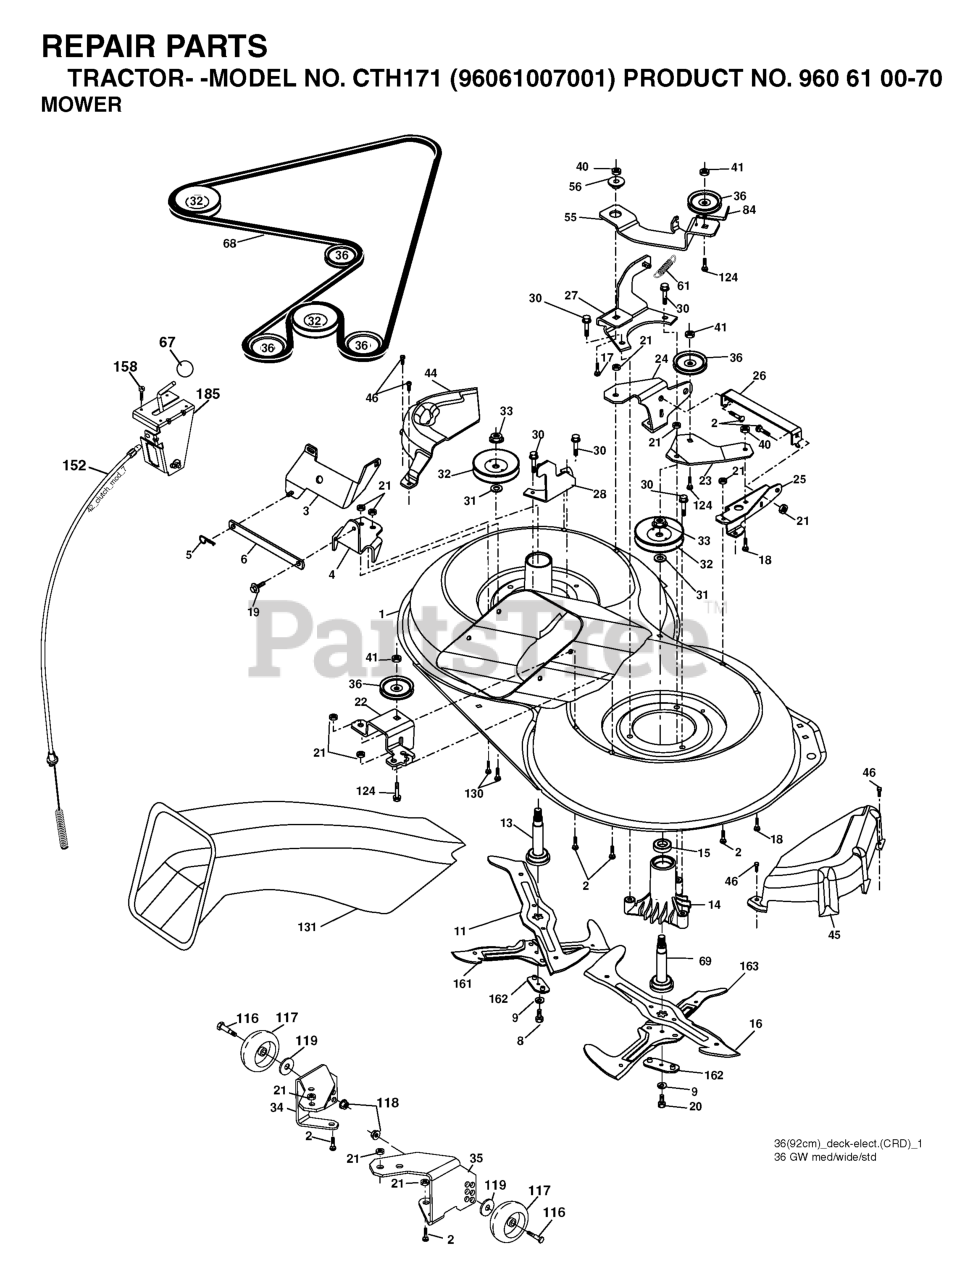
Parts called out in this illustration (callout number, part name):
2	RP BOLT 5/16-18 X3/4 ZN/YEL GR
5	RETAINER-SPRNG RB
6	BAR.SWAY.92.CRD
8	BOLT.3/8-24X1.25 GR8
9	LOCKWASHER
13	SHAFT ASM VENT
14	HOUSING.MANDREL.VENTED (MACHD)
17	BOLT.3/8-14X1.25
19	BOLT SHD 5/16-18
20	BOLT.3/8-24X1.25GR8. LHTHRD
21	LOCKNUT
26	SUPPORT
30	SCREW, WASHER HEAD
31	WASHER.SPACER.MANDREL
32	PULLEY, MANDREL
33	NUT.FLANGE.LOCK.TOP
36	PULLEY.IDLER.4.25
41	NUT LOCK FLG 3/8-16 UNC
45	COVER.MANDREL.RH.CRD
46	SCREW.1/4-20X5/8
55	ARM.IDLER.92 CRD.2006
56	SPACER.RETAINER.MOWER
61	SPRING.TENSION.BELT
67	KNOB T (3/8 HOLE)
68	BELT.DRIVE.92CM.CRD.2006
69	SHAFT.ASM.W/LWR.BRG.RH.THREAD
84	KEEPER, BELT IDLER
116	SHOULDER BOLT
117	RP WHEEL. GUAGE RALLY
118	LOCKNUT
119	WASHER.5/16.FLAT.STE.STD.
124	BOLT.3/8-16X1.50
130	BOLT.CARR.SQNK.5/16-18UNC.X3/4
131	CHUTE BAGGER
158	SCREW
169	COVER TERMINAL BATTERY
185	HEAD ASM. CABLE CLUTCH
